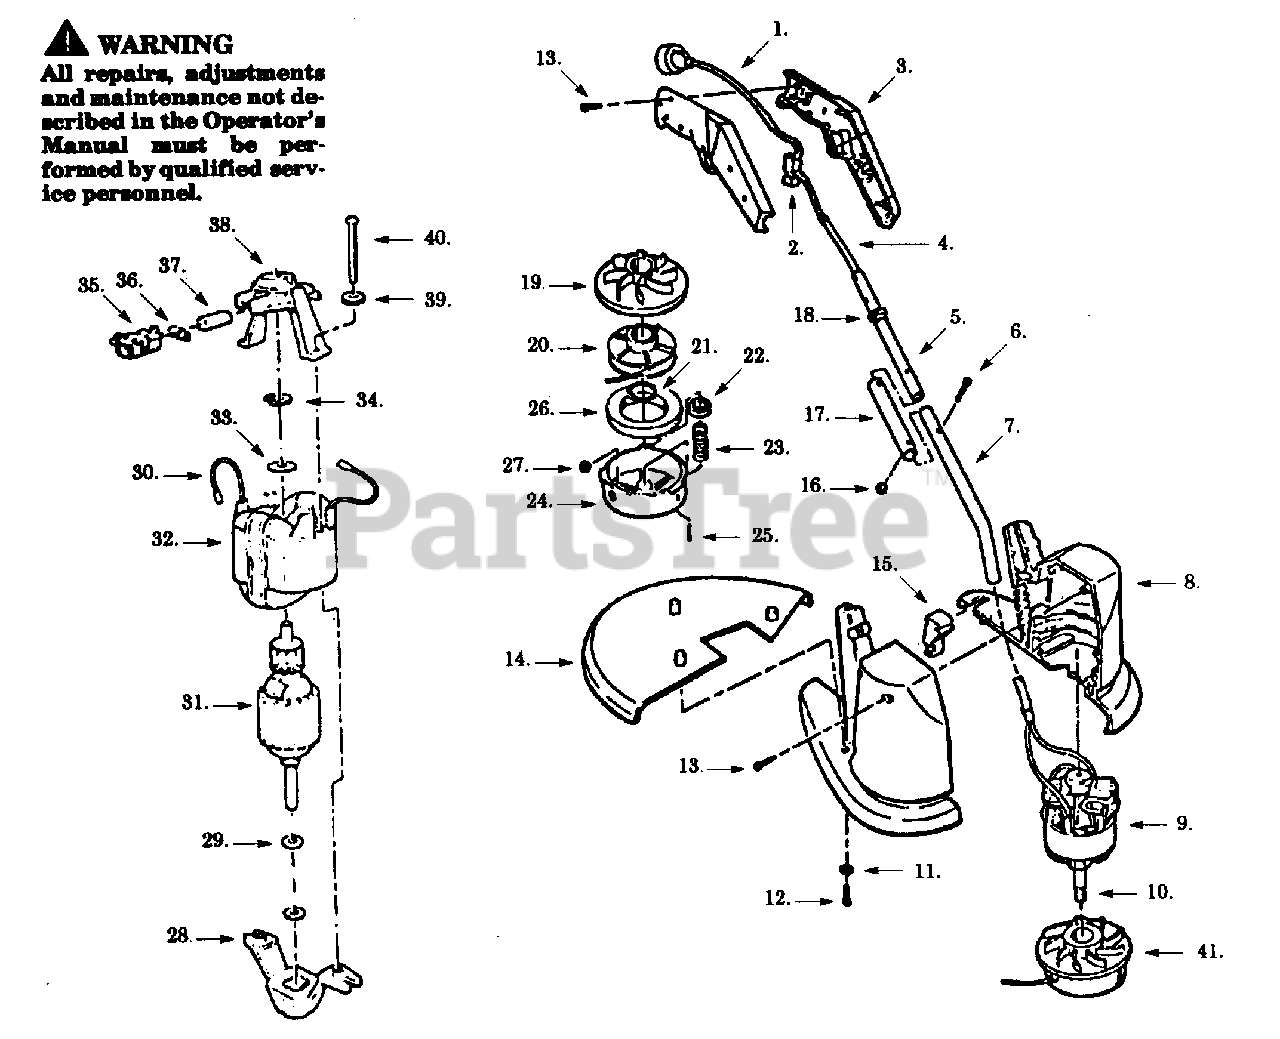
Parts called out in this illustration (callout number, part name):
1	Power Cord
3	R.H./L.H. Handle
5	Upper Tube
7	Lower Tube
8	R.H./L.H. Housing
10	Drive Adapter
15	Blade Retainer
17	Outer Tube
19	Rear Plate
20	Spool & Line
22	Adapter Nut
24	Hub Ass'y.
25	Cotter Pin
26	Foam Pad
28	Endbell Ass'y. (Drive)
30	Leadwire Ass'y.
31	Armature Ass'y.
32	Field Ass'y.
34	Retainer Ring
35	Brush Holder
36	Brush Spring
38	Endbell Ass'y. (Brush)
39	Lockwasher
41	Cutting Head Ass'y.
